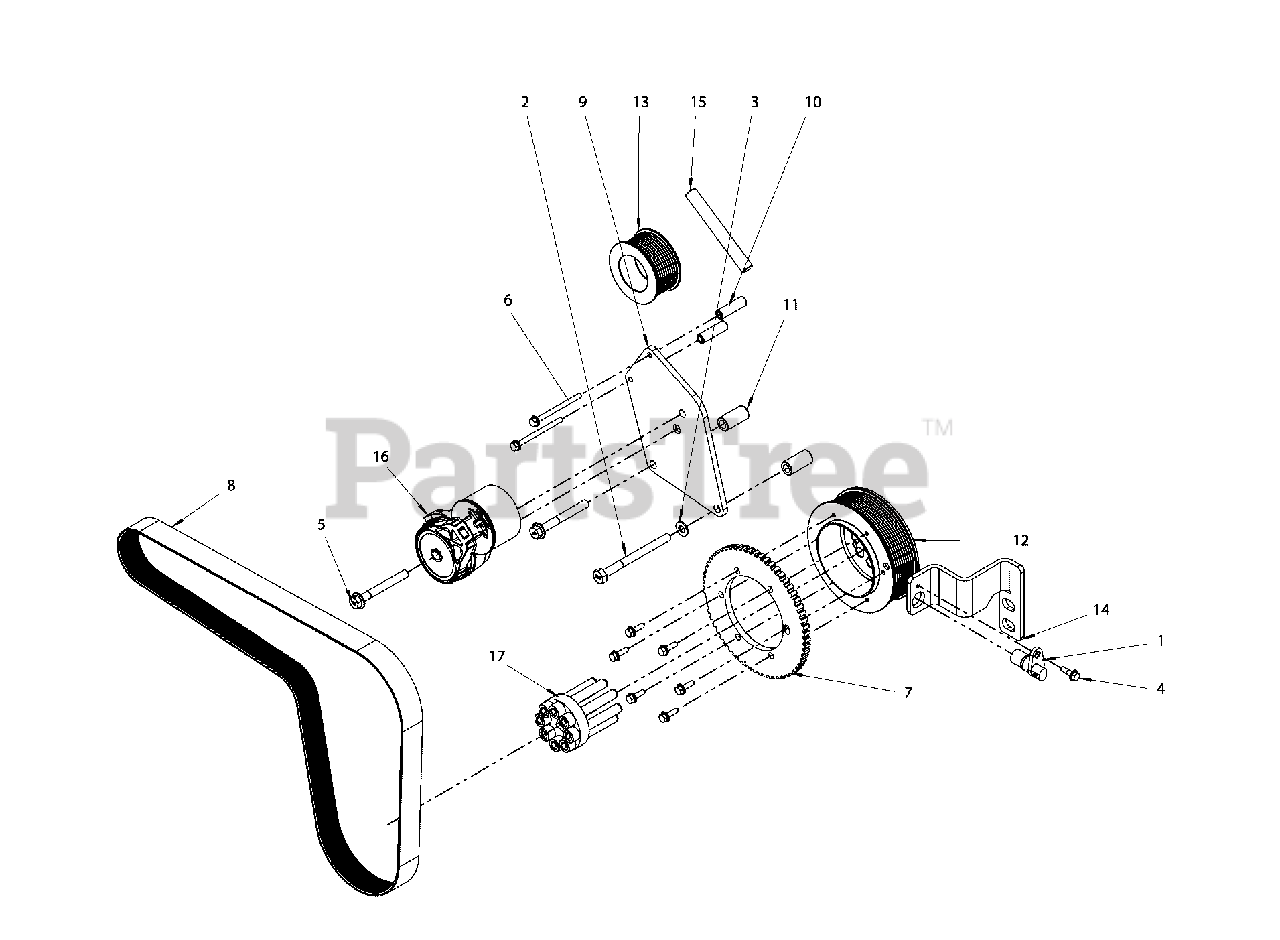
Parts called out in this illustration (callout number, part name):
1	SPEED SENSOR
2	* BOLT
3	* WASHER
4	* BOLT
5	* BOLT
6	* BOLT
7	* TIMING WHEEL
8	BELT
9	* TENSIONER MOUNT
10	* SPACER
11	* SPACER
12	CRANK PULLEY
13	ALTERNATOR PULLEY
14	* BRACKET
15	* SLEEVE
16	TENSIONER
17	* SQUARE DRIVE
